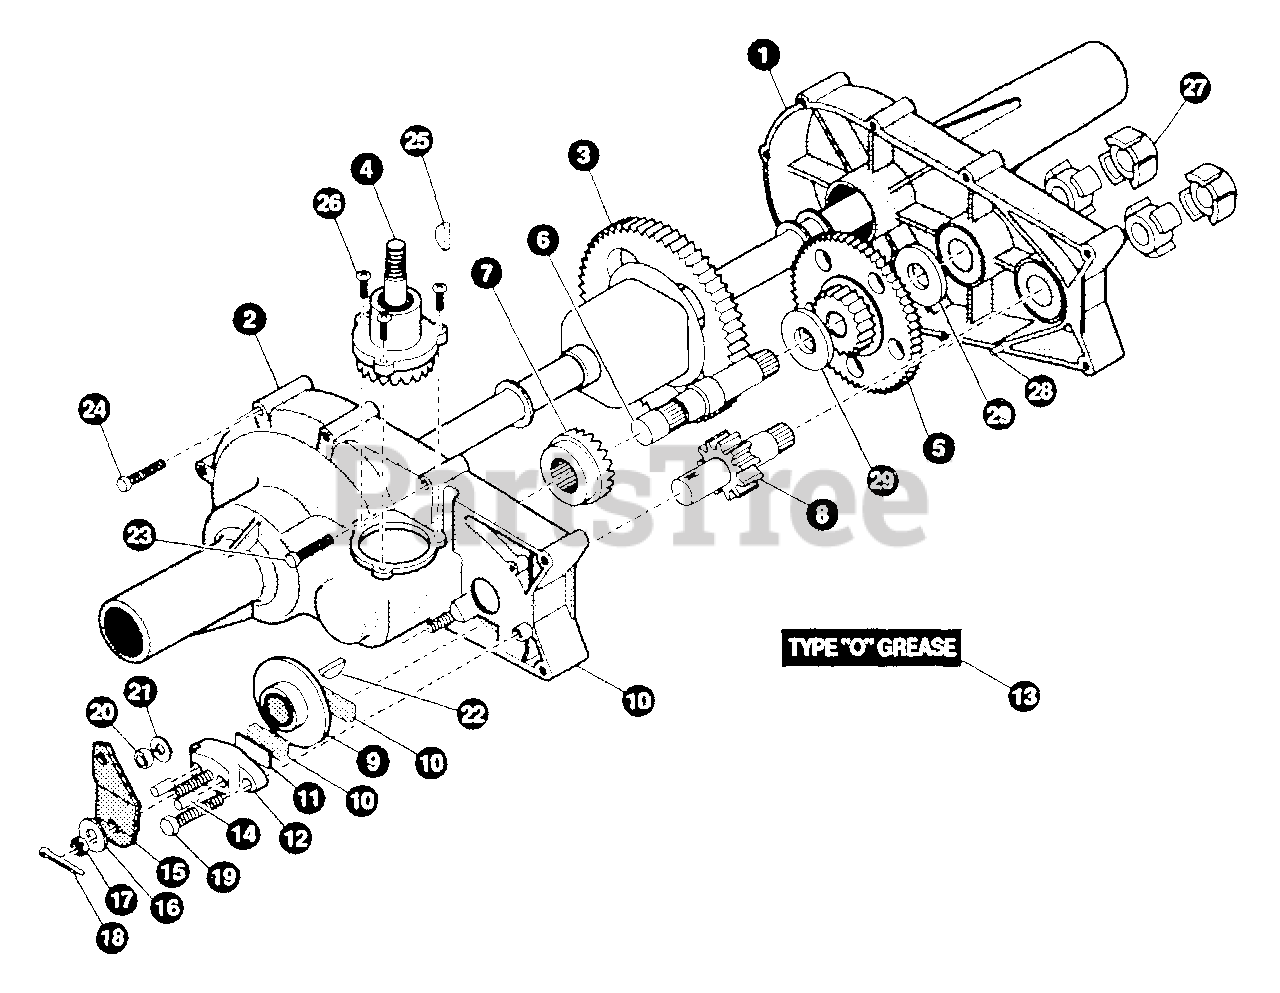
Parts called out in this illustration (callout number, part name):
1	HOUSING HALF, LH
2	HOUSING HALF, RH
3	GEAR, DIFFERENTIAL
4	SHAFT, INPUT
6	SHAFT, DRIVE
7	GEAR, DRIVE PINION
8	SHAFT, PINION
9	DISC, BRAKE
10	PUCK, BRAKE
11	PLATE, PUCK
12	BRAKE, YOKE
13	TYPE "O" GREASE
14	PIN, BRAKE ACTUATING
15	ARM, BRAKE ACTUATOR
16	WASHER, FLAT
17	NUT, CASTLE
18	PIN, COTTER
19	BOLT, HEX W/PATCH
20	NUT, HEX
21	WASHER, SPRING LOCK
22	KEY, HI-PRO
23	BOLT, HEX SELF-TAP
24	BOLT, HEX SELF-TAP
25	KEY, HI-PRO
26	SCREW, HEX W/PATCH
27	COUPLING
28	PIN ROLL
29	WASHER, FLAT
